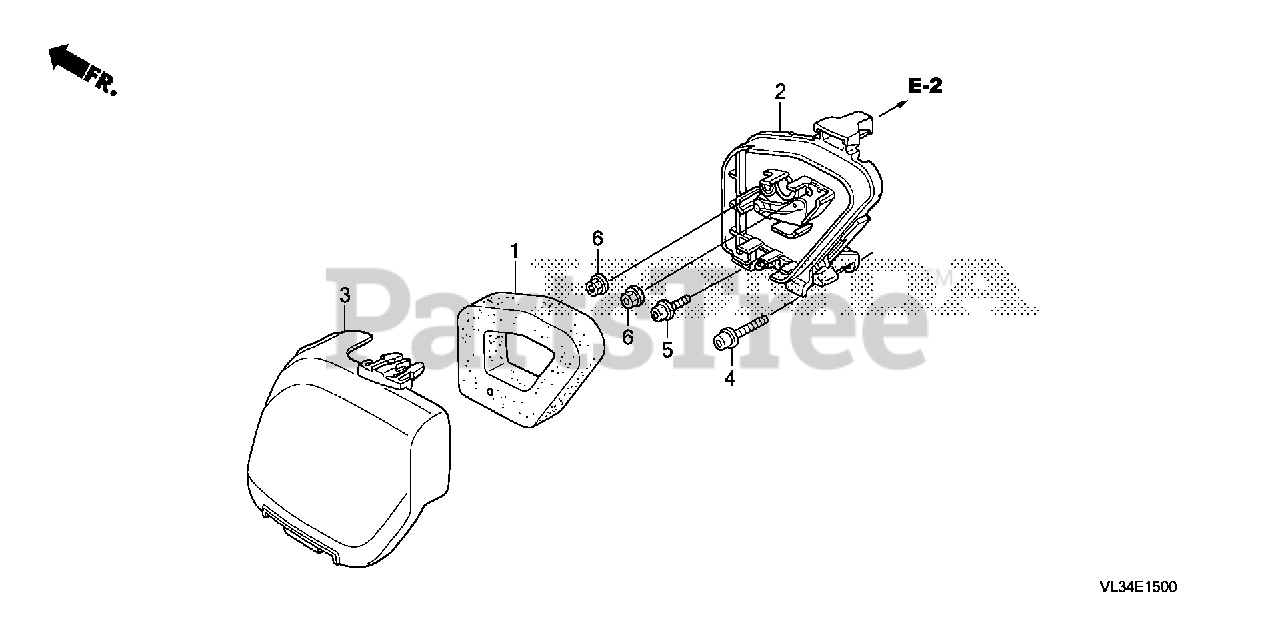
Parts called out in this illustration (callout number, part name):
1	ELEMENT, AIR CLEANER
2	HOUSING, AIR CLEANER
3	COVER, AIR CLEANER
4	BOLT, SOCKET (5X25)
5	BOLT, SOCKET (5X16)
6	NUT, FLANGE (5MM)
